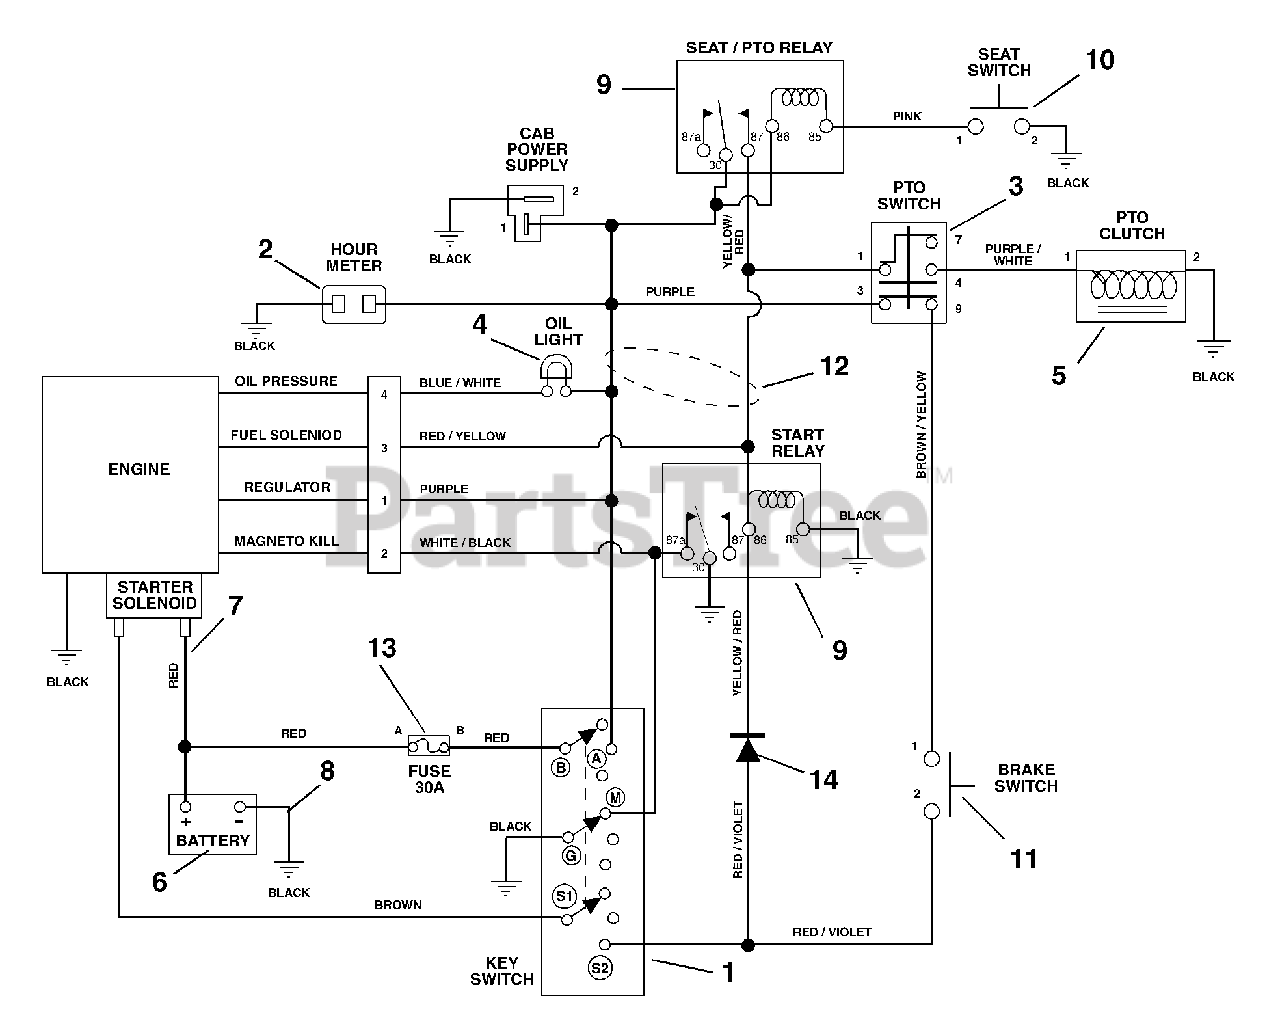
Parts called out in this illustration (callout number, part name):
1	Key Switch
2	Hour Meter
3	Switch, Clutch
4	Light-Indicator
5	Electric Clutch
6	Battery with Tube
7	22" Cable
8	Ground Cable
9	Relay
10	Seat Switch
11	Switch-Single Pole
12	Harness, Z 6-Pin Harness
13	Fuse, 30 Amp
14	Molded Diode Plug-Black 1-Amp
